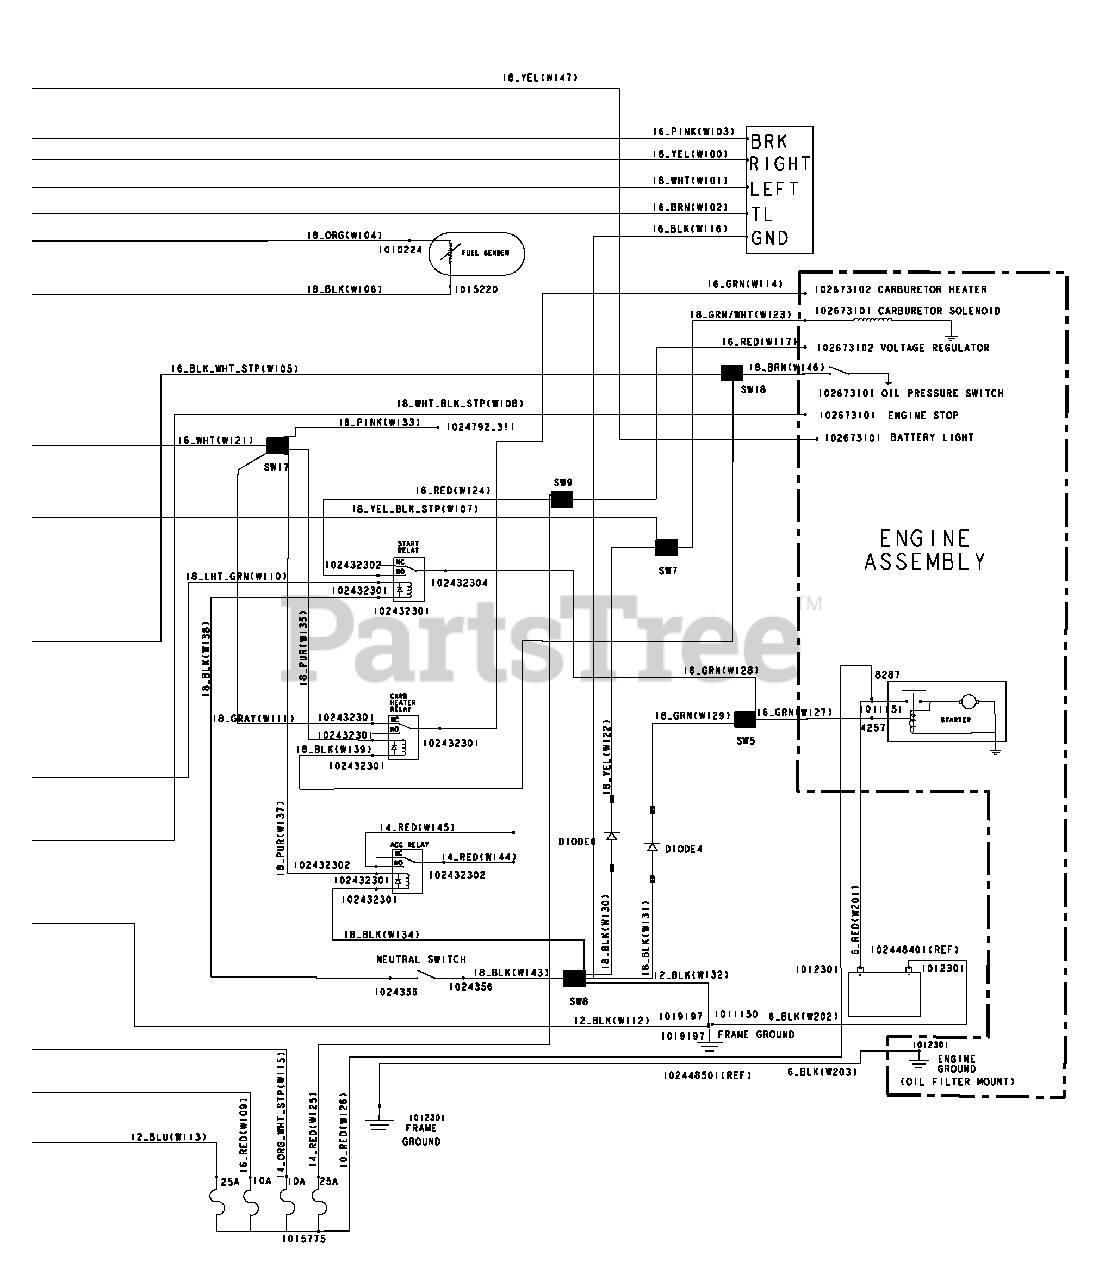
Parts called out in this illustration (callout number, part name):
1	Diode, General Purpose, 6.0a
2	Harness, AWD, Kawasaki, Stretch
3	Asm, Switch, Limit, Awd
